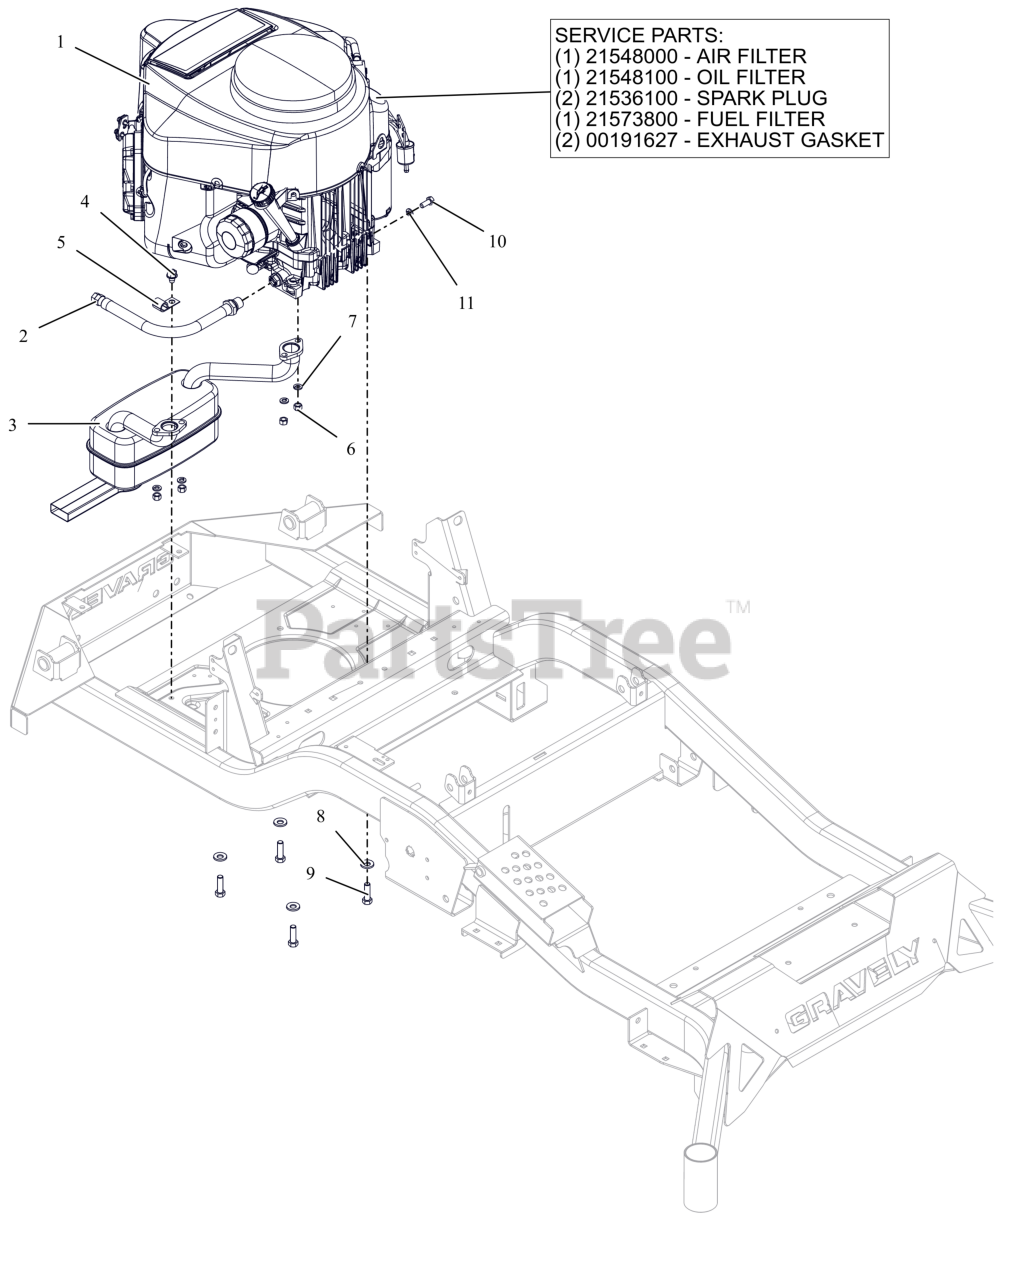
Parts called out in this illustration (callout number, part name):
1	ENGINE, KAWASAKI FR730 24HP
1	AIR FILTER, KAWASAKI FR
1	OIL FILTER, KAWASAKI FR
1	PLUG, SPARK
1	FUEL FILTER-KAWASAKI FR
1	GASKET, MUFFLER S/O
1	VALVE- T-TYPE OIL DRAIN
1	O-RING- OIL DRAIN VALVE
2	HOSE, OIL DRAIN
3	MUFFLER, KAWASAKI
4	SCR,TAP .375-16X.50 HWH TR ZCC
6	NUT-LK-TOP-FLG M8 ZCC
7	WSHR,LK-REG .312X.078 ZCC
8	WASHER, 3/8" SPRING DISC
9	BLT, HEX .38-16X1.25 G5 ZCC NT
10	BLT, HEX M8-1.25X20 G8.8 ZCC
11	WSHR,LK-REG .312X.078 ZCC
